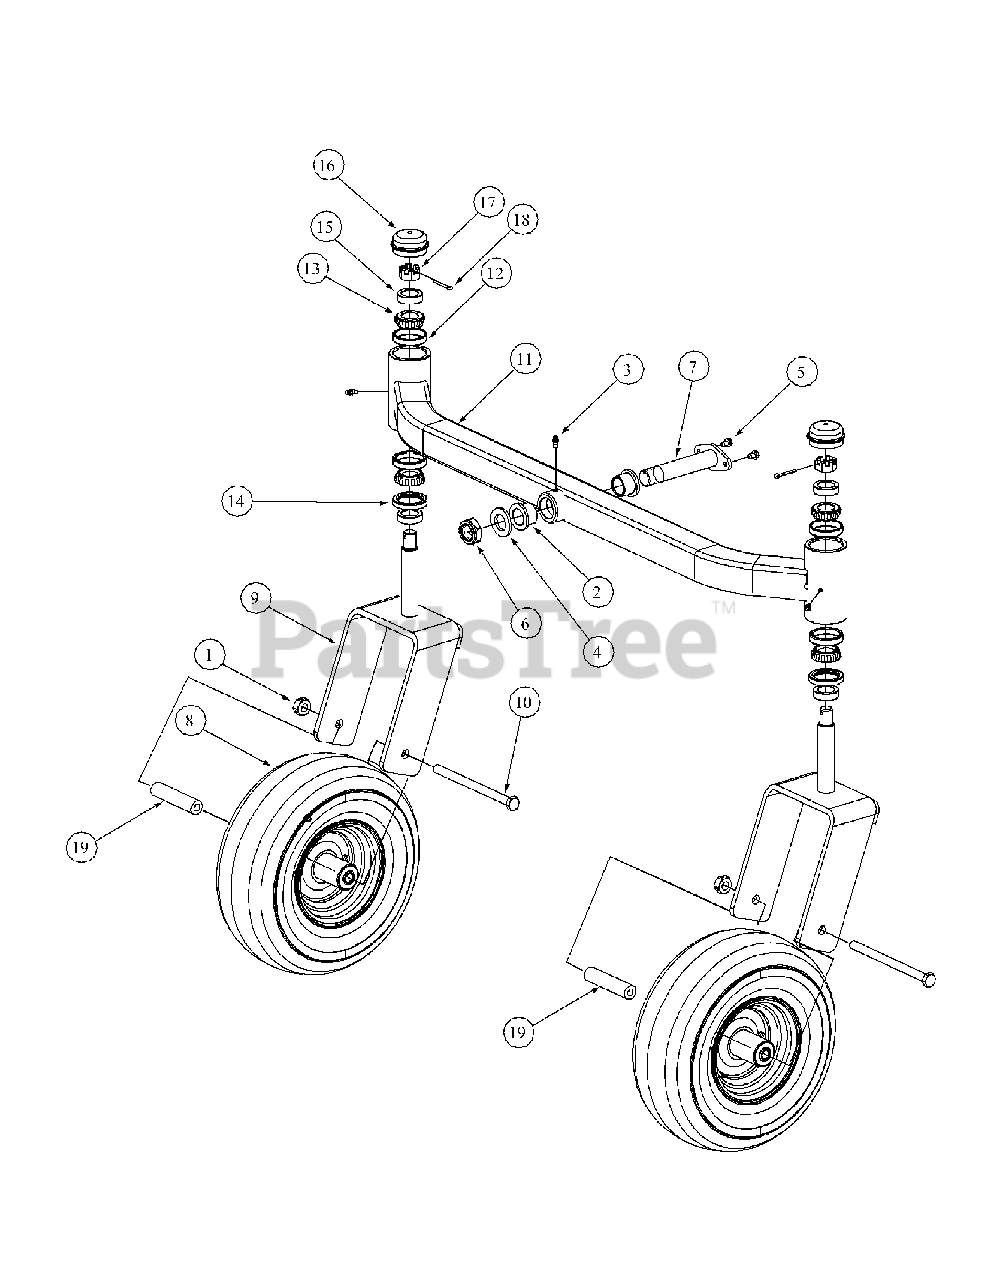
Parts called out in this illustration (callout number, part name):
1	Nut, 1/2-20, Center Lock
2	Flange Bearing
3	Grease Fitting
4	Special Washer
5	Screw TT, 1/4-20, .5 Hex Index Washer
6	Nut, Jam, 1.0-14, Insert Lock
7	Pin Weldment
8	Wheel, 13 x 5-6, White
8	Tire, Smooth, 13x5.00-6, 4-ply
9	Bracket Assembly, Caster Mount
10	HHCS, 1/2-20, 7.00
11	Front Axle Assembly
12	Cup Bearing
13	Bearing Cone
14	Seal
15	Ring Seal
16	Grease Cap, 1.986 OD
17	Slotted Nut, 3/4-16
18	Cotter Pin, 5/32, 1.25
19	Wheel Spacer
